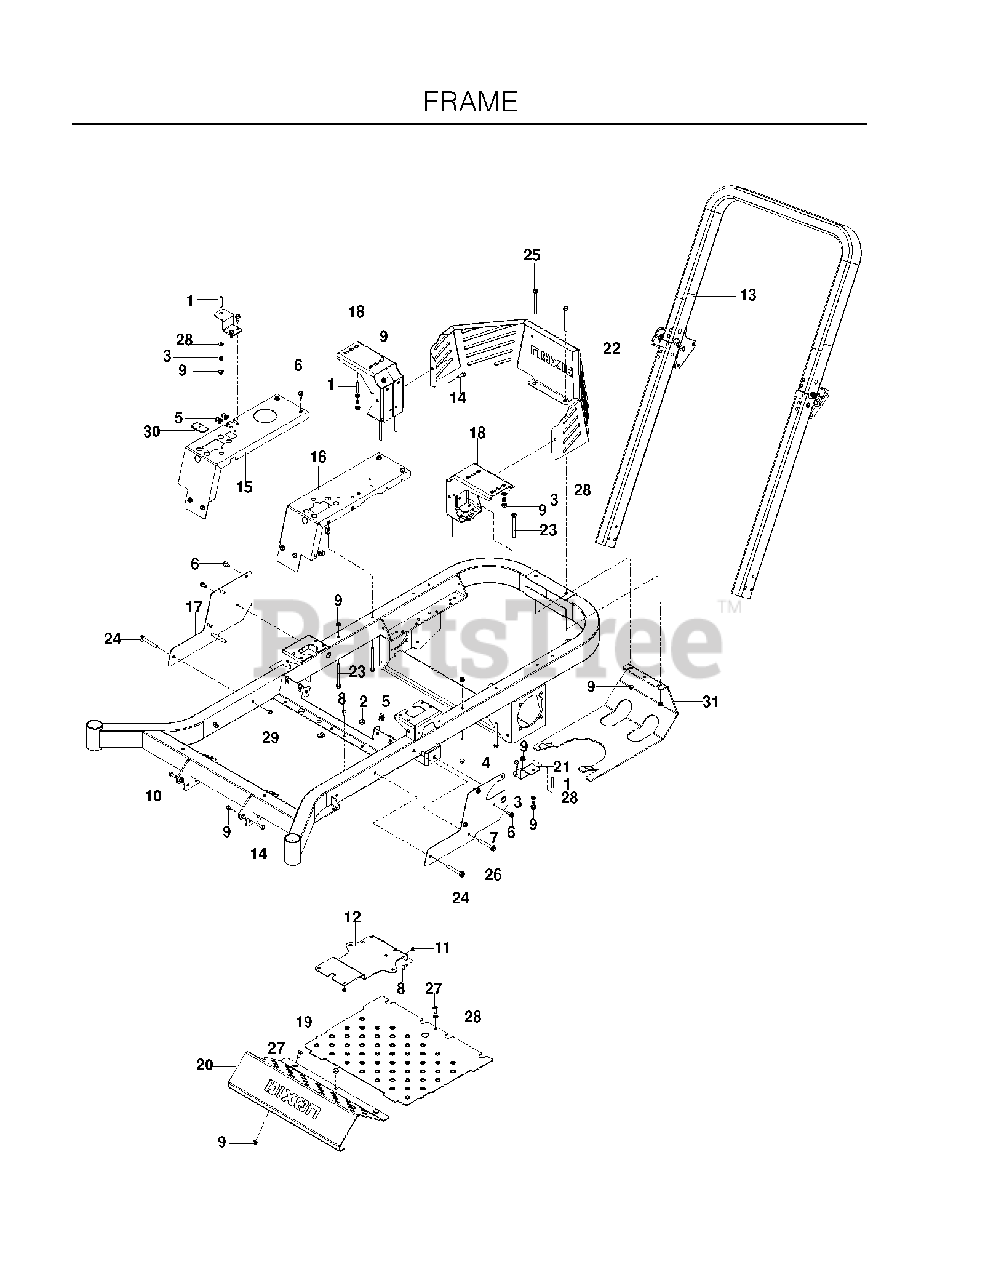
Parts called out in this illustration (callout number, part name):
1	STUD, 5/16C
2	GROMMET, BUMPER
4	Hex Washer Head Bolt, 5/16-18 X 3/4 Thread Forming
5	U-CLIP 5/16-18 NUT RETAINER
6	BOLT 5/16-18 X 3/4
7	SIDE, LT, BL
8	RHSSNB, 1/4-20X5/8
9	5/16-18 NYLOC FLANGE NUT
10	FRAME, BLUE W/DECALS
11	NUT 1/4-20 NYLOC
12	BATTERY MOUNT
13	ASSEMBLY, ROPS
14	HCS 5/16C X 1
15	PANEL, FILLER, RT, DK BLUE
16	PANEL, FILLER, LT - BLUE
17	SIDE, RT, BL
18	MOUNT, TANK, RR
19	FLOOR PAN W/DECALS
20	PLATE.FOOTREST.RAM.DARK.BLUE
21	SUPPORT, TANK, FT, BLK
22	GUARD, REAR, BLUE
23	HHFS 5/16-18 X 3 3/4
24	HHFS 3/8-16 X 2 3/4
25	CAPSCREW 5/16 X 4-1/2 HED HEAD
26	HHFS 3/8-16 X 2.5 GR 5 ZD
27	RHSNB 5/16C X 1
28	FLAT WASHER 5/16 SAE
29	NUT HEX 3/8-16 NYLON, THIN
30	PLUG DASH
31	GUARD, SKID, BLUE
